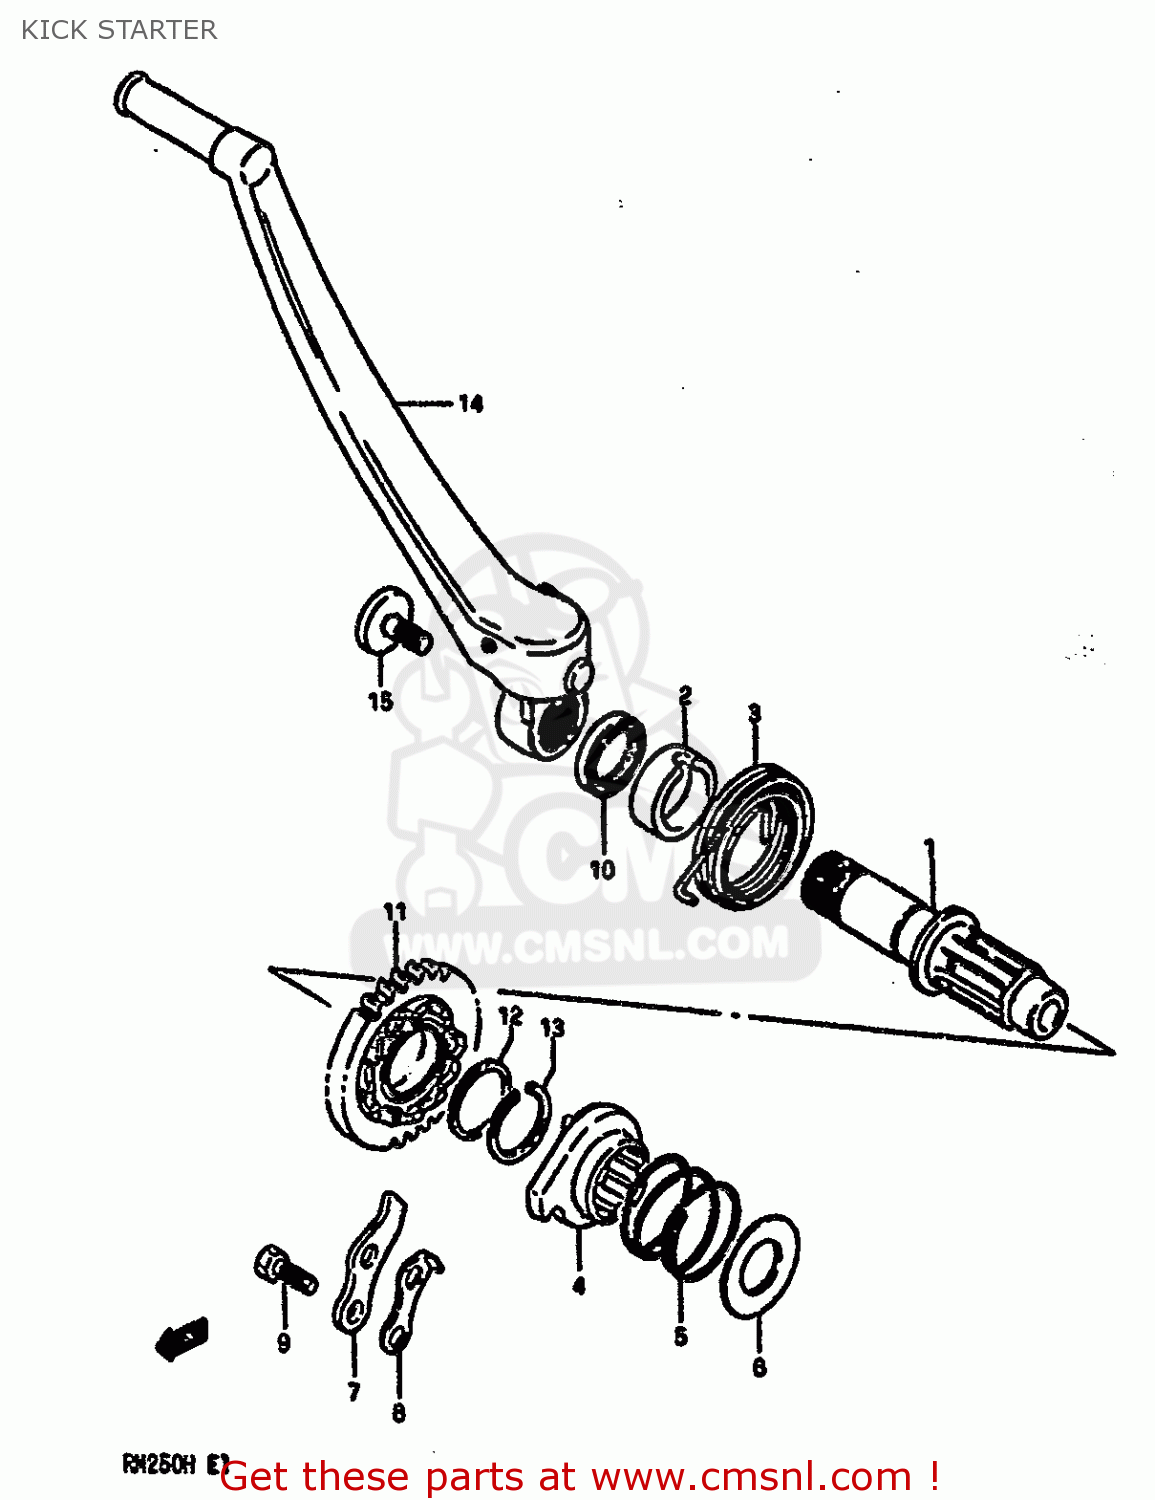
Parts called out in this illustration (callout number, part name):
1	SHAFT,KICK STARTER
2	GUIDE,KICK STARTER SHAFT
3	SPRING
4	STARTER,KICK
5	SPRING
6	WASHER
7	GUIDE,KICK STARTER
8	STOPPER,KICK STARTER
9	BOLT
10	SEAL,OIL(20X27X5)
11	GEAR
12	SHIM
13	CIRCLIP
14	LEVER ASSEMBLY,KICK STARTER
15	BOLT
